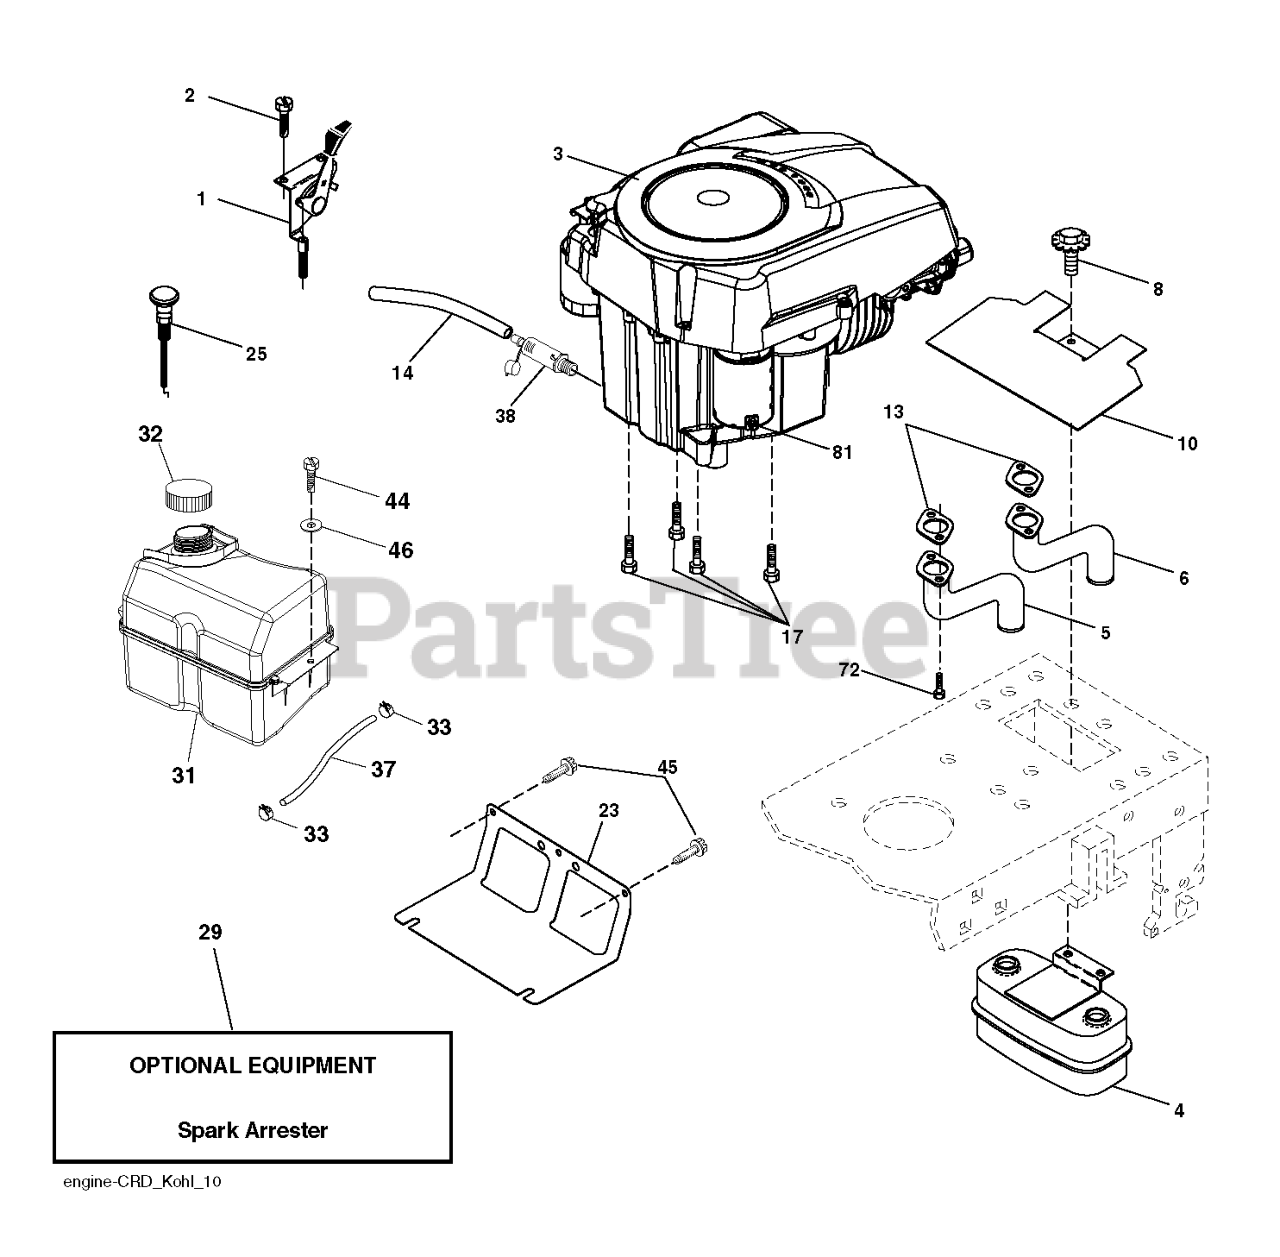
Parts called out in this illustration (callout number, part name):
1	THROTTLE CONTROL
2	SCREW.#10 X 0.750.BOS
4	MUFFLER.TWIN.CYL.LOW.TONE
5	RP.PIPE-EXHAUST LH
6	RP.PIPE-EXHAUST RH
8	BOLT.5/16-18UNCX3/4 W/SEMS.BLK
10	RP SHIELD HEAT MUFFLER
13	GASKET.EXHAUST.KOHL.CV18-CV26
14	TUBE, DRAIN OIL ASM.
17	SCREW 3/8-16X1
23	SHIELD.BROWNING.DBR.GUARD
25	CONTROL, CHOKE
29	KIT.SPARK ARRESTOR 794945 B&S
31	TANK.ASM.FUEL.FR.2.5GA.
32	CAP ASM.FUEL.2.25"FR.
33	HOSE CLAMP
37	LINE.FUEL.20
38	VALUE.OIL.DRAIN
44	SCREW HEXWSHR 1/4-20X3/4
45	SCREW, 3/8-16X3/4
72	SCREW.SOCKET HD.5/16-1
81	NUT
